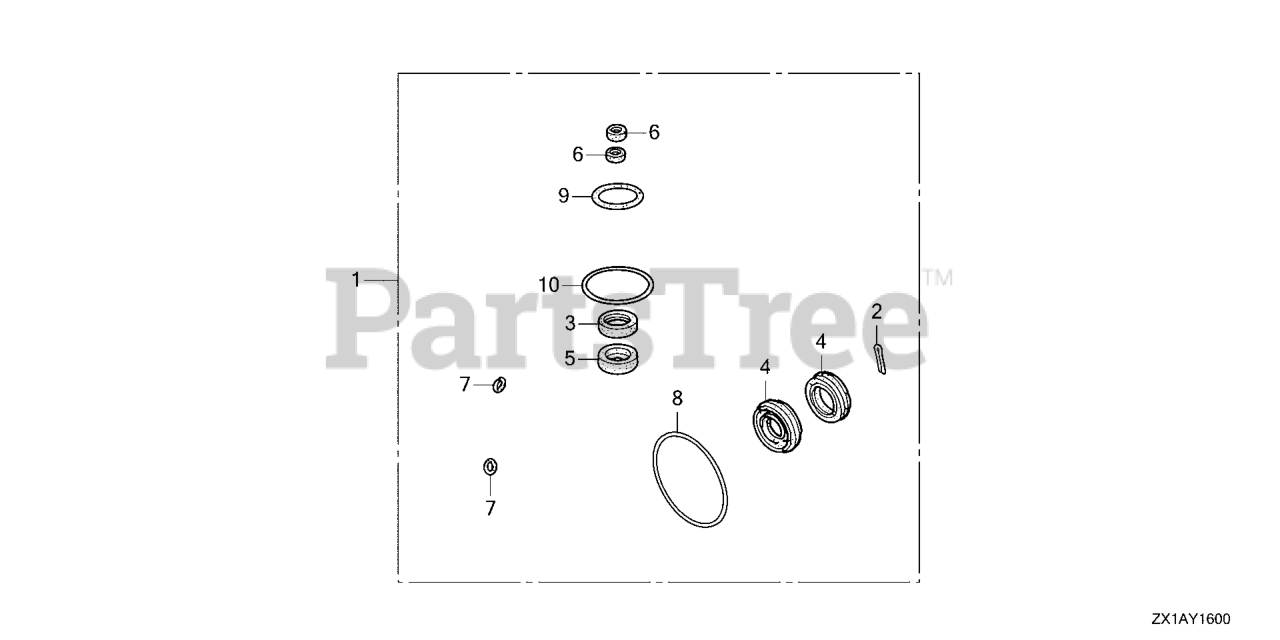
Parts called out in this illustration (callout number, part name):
1	CASE KIT, GEAR
2	PIN, SPLIT (4.0)
3	SEAL, WATER (23X36X8)
4	SEAL, WATER (30X45X7)
5	SEAL, WATER (23X36X6)
6	SEAL, WATER (12X21X6)
7	O-RING (6.9X1.45)
8	O-RING (105X3.1)
9	O-RING (55.6X3.5)
10	O-RING (58.5X3.5)
